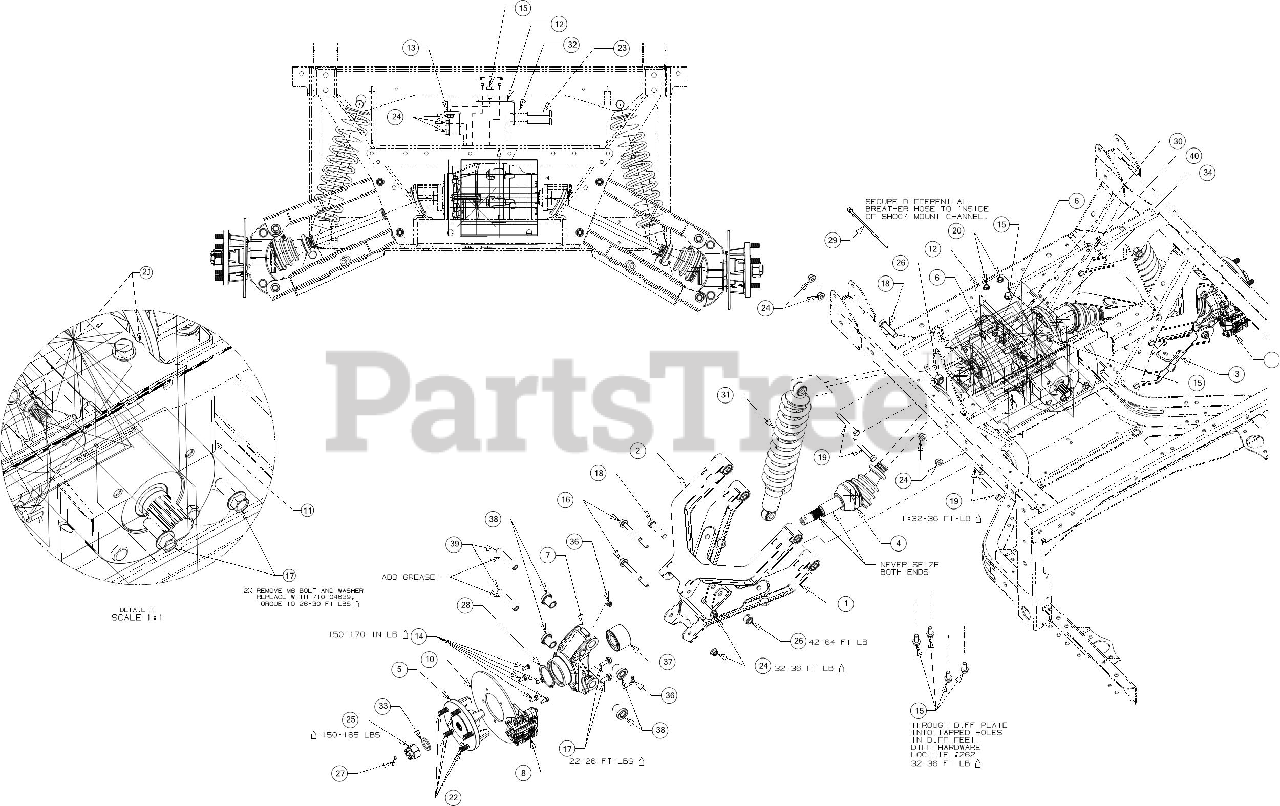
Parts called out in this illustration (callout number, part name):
1	LOWER CONTROL ASSEMBLY
2	UPPER CONTROL ASSEMBLY
3	LOWER CONTROL ASSEMBLY
4	CV JOINT AXLE:ASSEMBLY
5	WHEEL HUB ASSEMBLY
6	UV REAR DRIVE KIT
7	4X4 REAR HOUSING
8	FRONT BRAKE CALIPER ASSEMBLY (RH)
9	FRONT BRAKE CALIPER ASSEMBLY (LH)
10	BRAKE DISC 8.00 x .188
11	DIFFERENTIAL BRACKET
12	REAR DIFFERENTIAL MOUNT
13	REAR DIFFERENTIAL BRACKET
14	SCREW 1/4-20 x .62 SPEC GR5
15	SCREW 3/8-16 x .875 GR5
16	SCREW 3/8-16 x 4.00 GR5
17	SCREW M8 x 1.25 x 25MM GR8.8
18	SCREW 1/2-13 x 2 GR5
19	SCREW 3/8-16 x 3 GR8
20	SCREW 5/16-18 x .500
21	SCREW 3/8-16 x 3/4
22	STUD 7/16-14 x 1.6
23	SCREW 3/8-16 x 2.25 GR5
25	SLOTTED NUT22X1.5
26	HEX LOCK NUT NYLON
27	COTTER PIN-5/32 DIA
28	RETAINING RING
29	CABLE TIE
30	HOSE CLAMP
32	FLAT WASHER .385X.870X.090
33	THRUST WASHER
36	45 DEGREE LUBE FITTING 1/4-28 TAPER
37	DOUBLE ROW BEARING
38	FLANGE BEARING .625 ID
40	FUEL HOSE LOW PERMEATION
